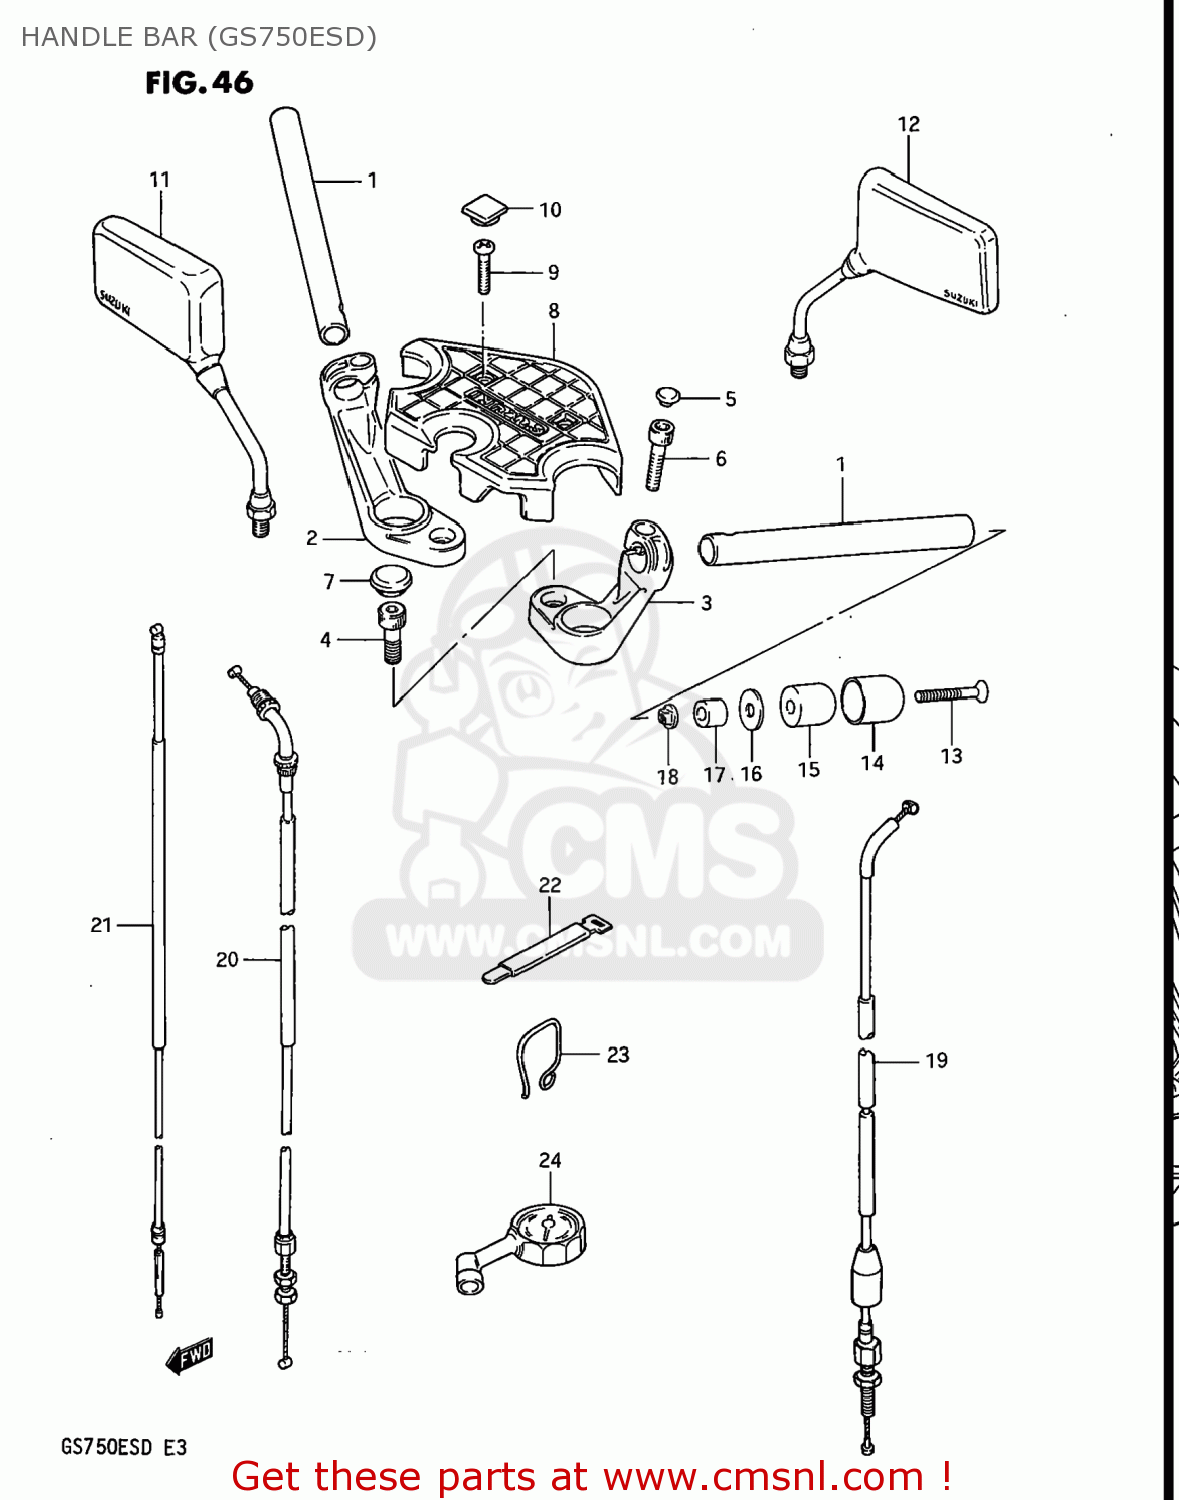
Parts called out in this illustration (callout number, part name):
1	HANDLEBAR
2	HOLDER,HANDLEBAR,RIGHT
3	HOLDER,HANDLEBAR,LEFT
4	BOLT
5	BOLT 10X50
6	WASHER
7	CLIP
8	CAP(OD:14.5)
9	BOLT 8X35
10	WASHER
11	CAP,GRIP END
12	PAD,HANDLE
13	SCREW (6X35)
14	WASHER
15	PLUG
16	MIRROR ASSEMBLY,RIGHT
17	MIRROR ASSEMBLY,REAR VIEW
18	SCREW 6X65
19	CAP,BALANCER
20	BALANCER,HANDLE
21	SPACER,BALANCER
22	EXPANDER,BALANCER
23	NUT
24	CABLE ASSY,CLUTCH
25	CABLE ASSY,THROTTLE
26	CABLE COMP,STARTER
27	CLAMP
28	GUIDE,CABLE/HARNESS
29	GAUGE ASSY,AIR PRESSURE
